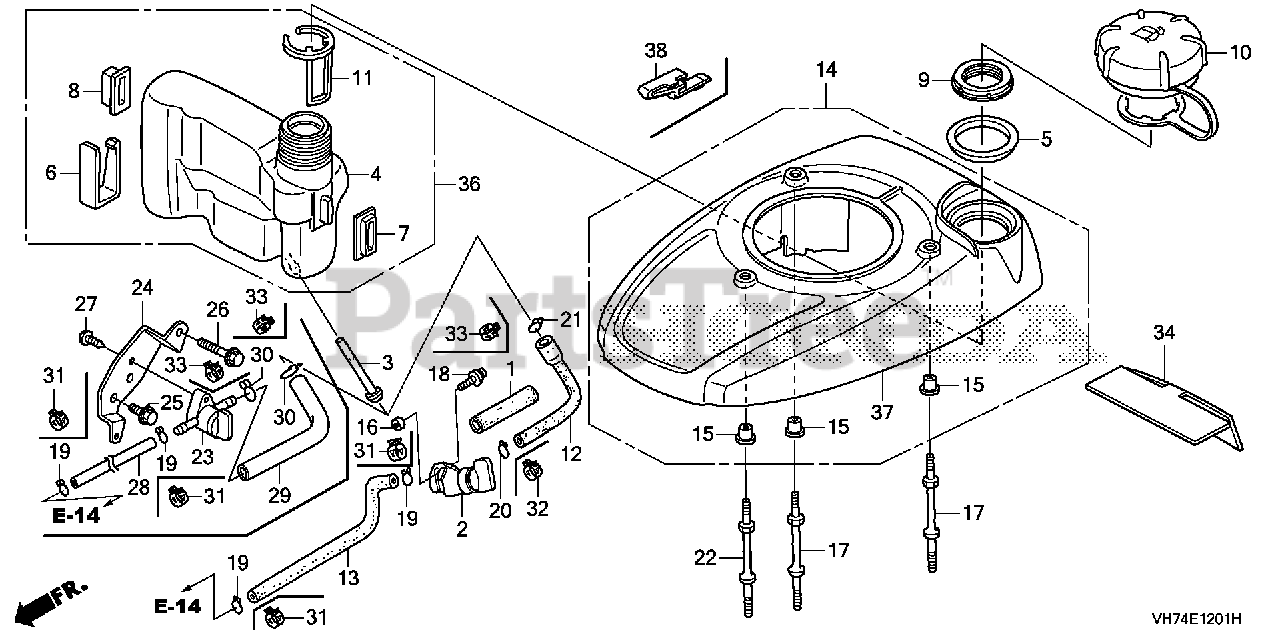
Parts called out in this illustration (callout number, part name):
3	FILTER, FUEL
4	TANK, FUEL
5	SEAL, FUEL FILLER NECK
6	CLIP, TANK MOUNTING
7	RUBBER A, TANK MOUNTING
8	RUBBER B, TANK MOUNTING
9	NUT, TANK MOUNTING
10	CAP ASSY., FUEL TANK
11	GAUGE, FUEL LEVEL
14	COVER, FAN *R280* (POWER RED)
15	COLLAR, FAN COVER
17	BOLT, STUD (FAN COVER)
22	BOLT, STUD (FAN COVER)
23	PETCOCK ASSY.
24	STAY, PETCOCK
25	BOLT, FLANGE (6X12) (CT200)
26	BOLT, FLANGE (6X28) (CT200)
27	SCREW, TAPPING (5X12) (PO)
28	TUBE, FUEL (4.5X110) (FKM)
29	TUBE, FUEL (7.3X160) (FKM)
31	CLAMP, TUBE (D8)
33	CLAMP, TUBE (D12)
36	TANK KIT, FUEL
37	COVER, FAN *R280* (POWER RED)
